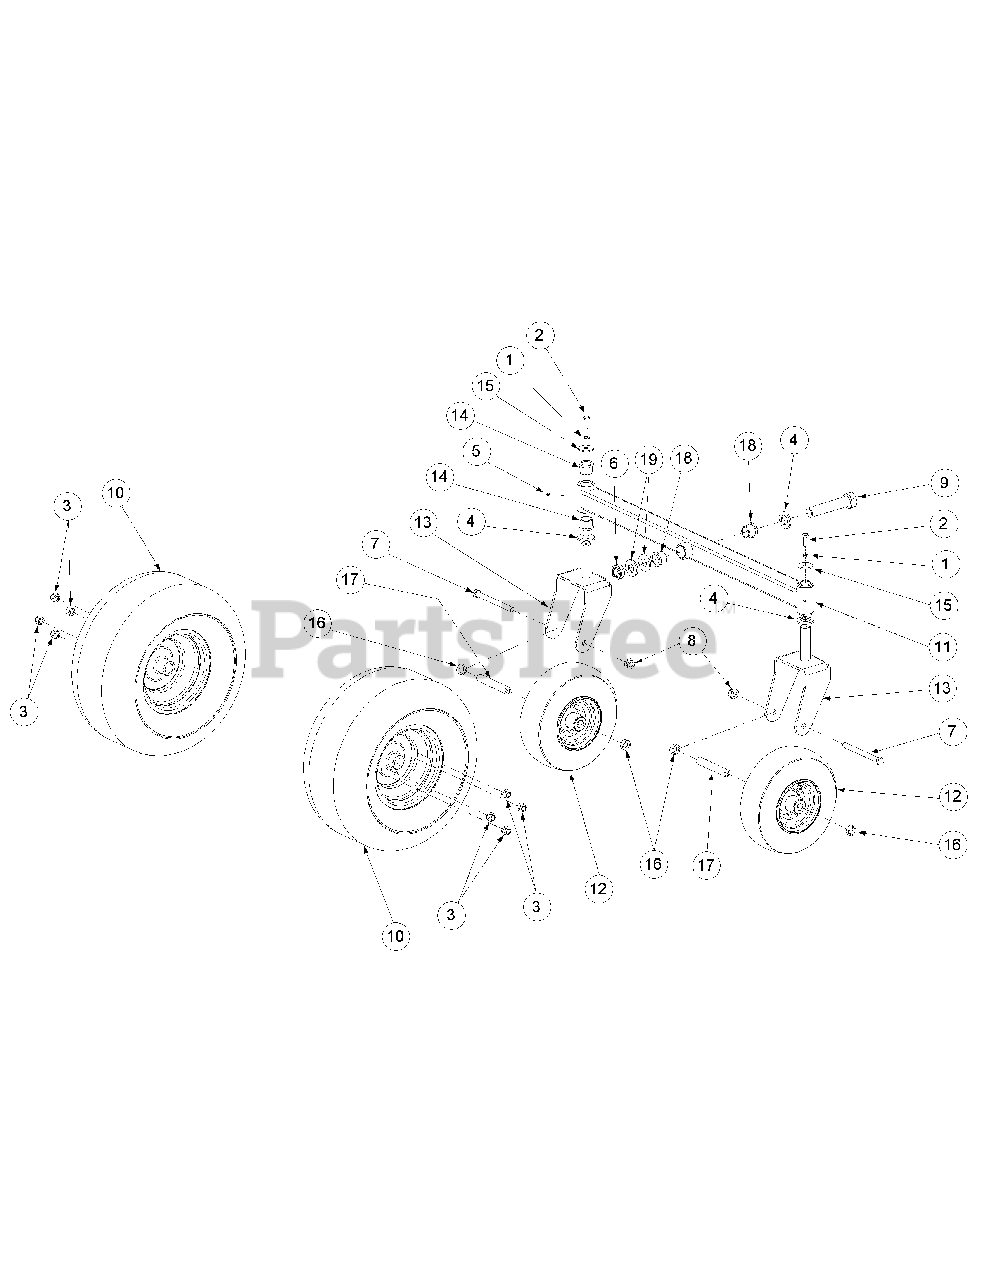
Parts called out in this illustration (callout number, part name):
1	Lock Washer, 3/8 Zinc
2	Hex Cap Screw, 3/8-16 x .88
3	Lug Nut, 1/2-20
4	Washer Special
5	Grease Fitting, 1/4-28 x 3/16
6	Nut Jam, 1.0-14, Nylon Insert
7	Hex Cap Screw, 1/2-20 x 5.50
8	Nut, 1/2-20, Center Lock
9	Hex Cap Screw, 1-14 x 5.0
10	Wheel Assembly, 18 x 9.5
11	Front Axle Assembly
12	Front Wheel Assembly
13	Castor Wheel Mounting Bracket
14	Flange Bearing, 1.0 ID
15	Flat Washer, .390 x 1.5 x .134
16	Spacer, .790 ID x .347 Lg
17	Wheel Spacer
18	Flange Bearing, 1.013 ID
19	Flat Washer, 1.00 ID x 2.25 OD x ,075
